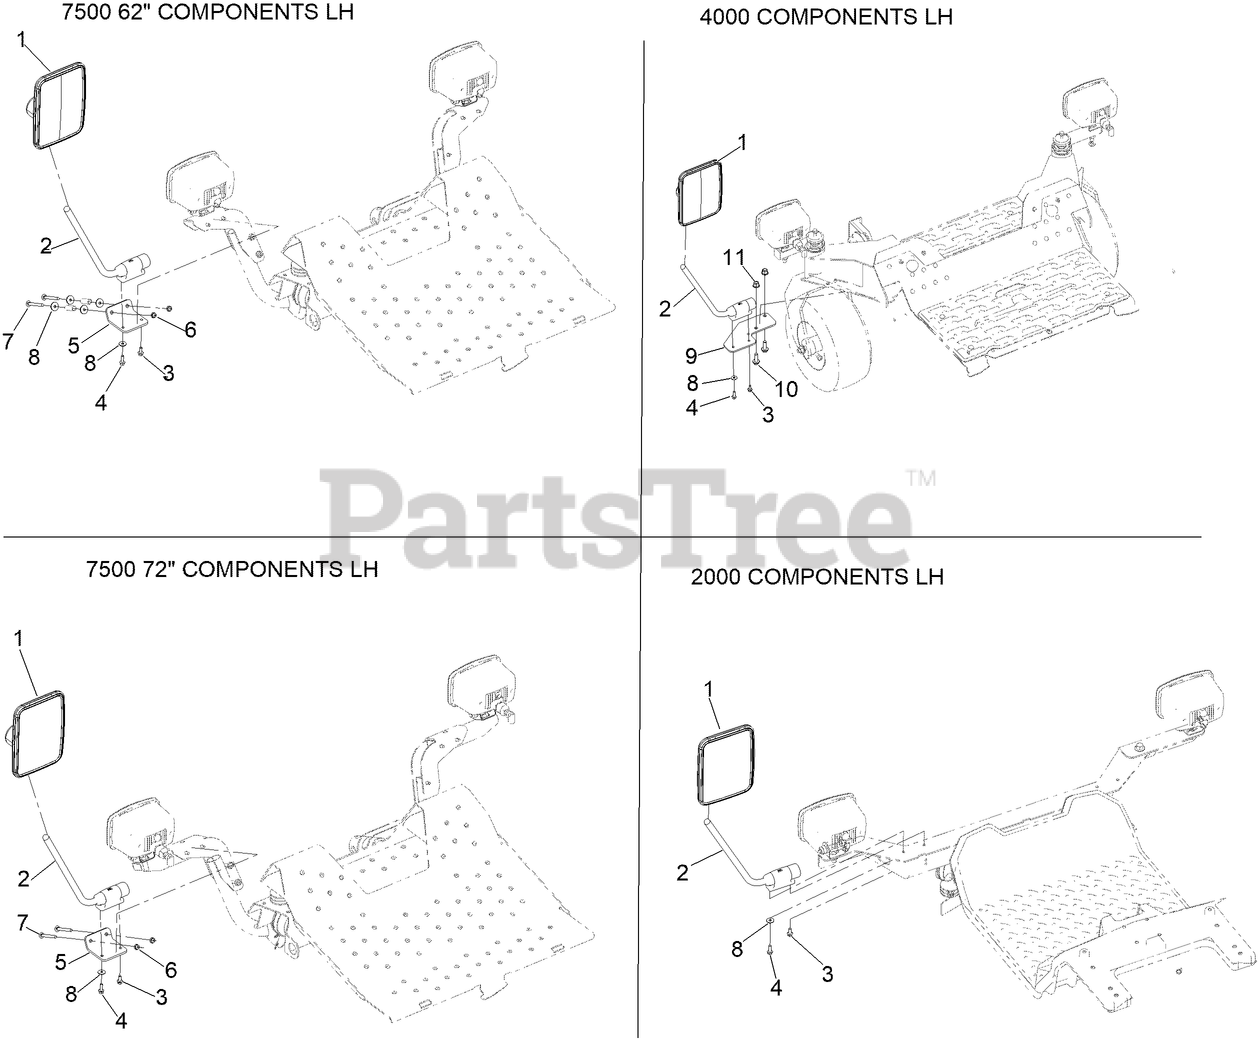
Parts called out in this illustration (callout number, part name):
1	SIDE MIRROR ASM
2	ARM-MIRROR
3	SCREW-HHF
4	SCREW-HHF
5	BRACKET-MIRROR, 7500
6	NUT-HF
7	SCREW-CARR
8	WASHER
9	PLATE-MIRROR, Z4000
10	SCREW-HHF
11	NUT-FLANGE, NI
